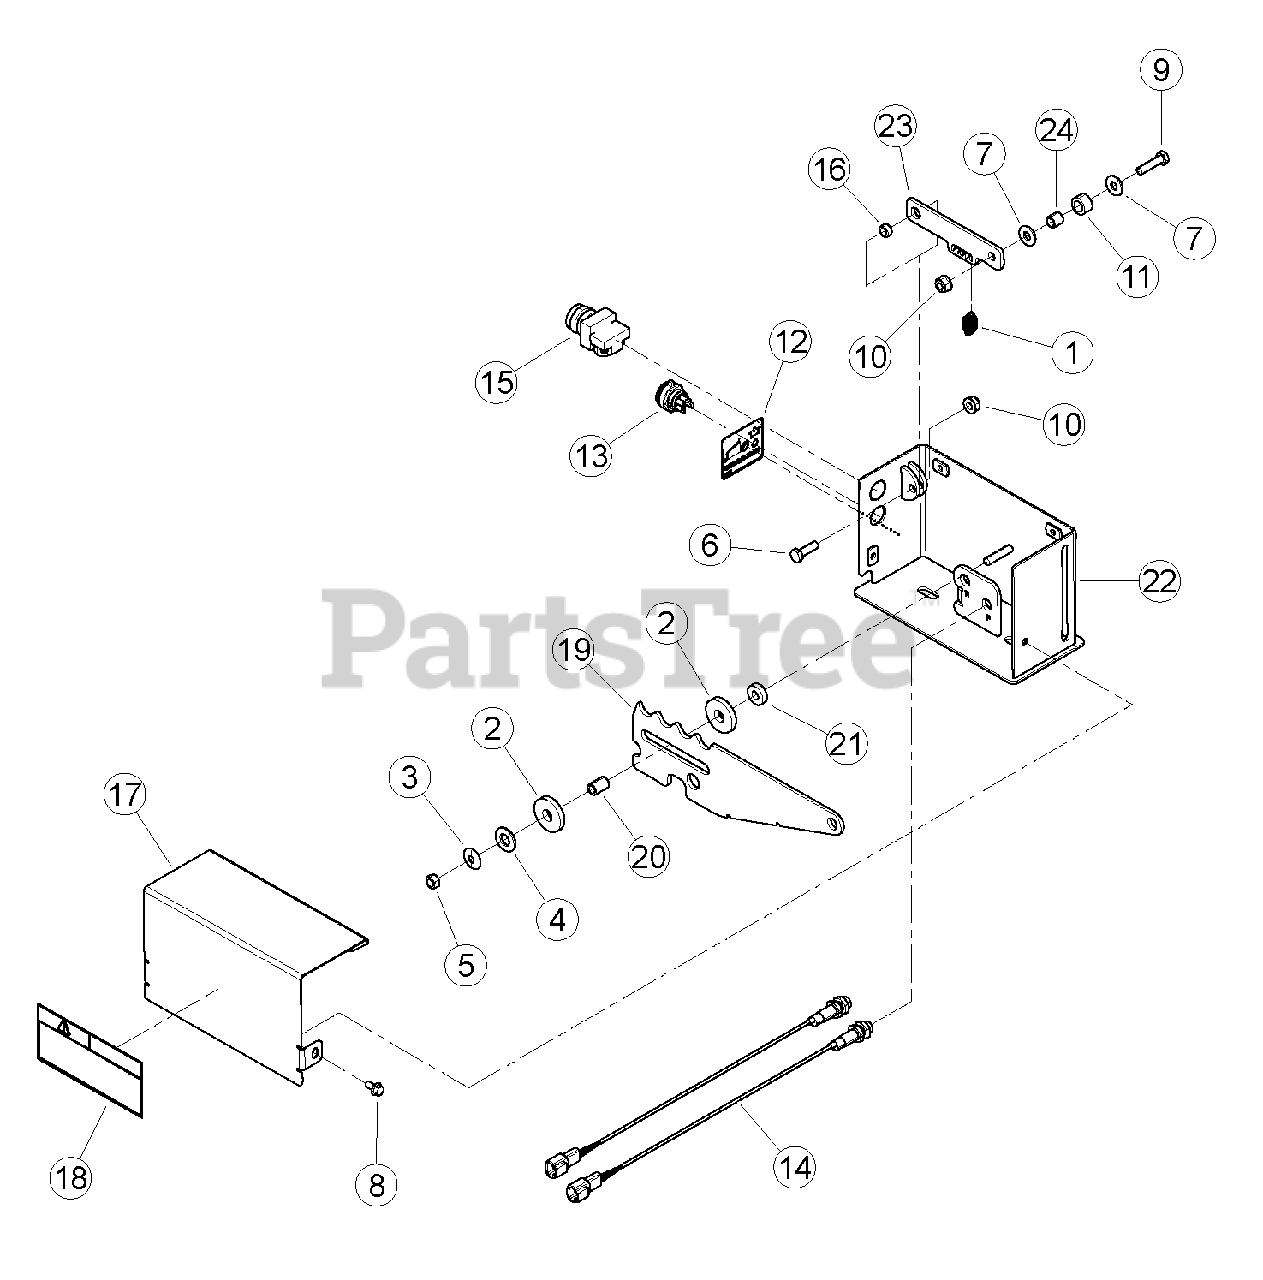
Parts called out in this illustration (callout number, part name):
1	SPRING, CONTROL BAR
2	WASHER, UHMW SPACER .515ID-1.50OD
3	WASHER, SPRING
4	WASHER, 1/2 SAE FLAT ZP
5	NUT, 5/16 CENTERLOCK NC ZP
6	BOLT, 5/16 X 1 HEX GR5 NC ZP
7	WASHER, 5/16 FLAT ZP
8	BOLT, 1/4 X 1/2 SERR FLANGE GR5 ZP
9	BOLT, 5/16 X 1-1/4 HEX GR5 NC ZP
10	NUT, 5/16-18 NYLOCK-FLANGE
11	ROLLER, NYLON .75 OD X .502 ID X .440
12	DECAL, RESET/OVERRIDE
13	LIGHT, LED TRI-COLOR
14	SENSOR, M12 PNP PROXIMITY (REPLACEMENT PART)
15	SWITCH, MOMENTARY IP65 NORMALLY OFF
16	SPACER, IDLER PIVOT
17	ASSEMBLY, CONTROL COVER W/ DECAL
18	DECAL, MULTILINGUAL MANUAL
19	BAR, SWITCH CONTROL
20	SPACER, .50 X .728
21	SPACER, .375 X .25
22	WELDMENT, SWITCH BOX
23	LINK, DETENT
24	SPACER, 1/2 OD X .35 ID X .47
